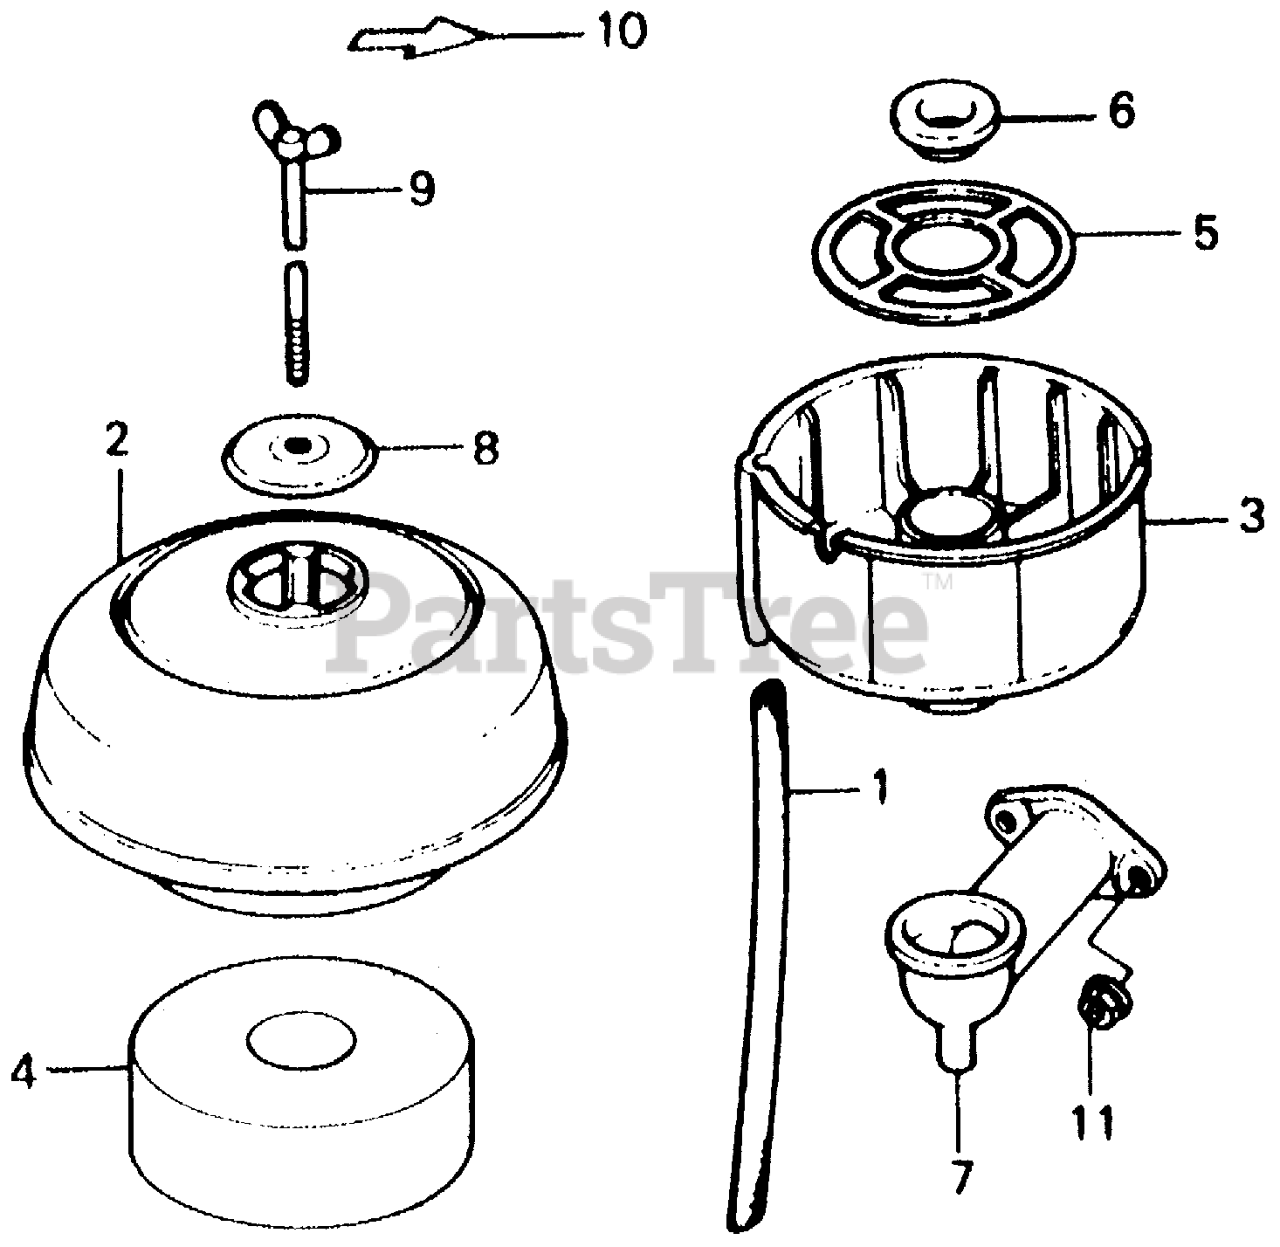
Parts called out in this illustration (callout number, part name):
1	TUBE, BREATHER
2	BODY, CLEANER
3	PAN, AIR CLEANER OIL
4	ELEMENT, AIR CLEANER
5	GRID, AIR CLEANER
6	COLLAR, AIR CLEANER
7	ELBOW, AIR CLEANER Use up to Engine SN 1013844.
8	CAP, AIR CLEANER
9	BOLT, AIR CLEANER
10	MARK, CHOKE
11	NUT, FLANGE (6MM)
